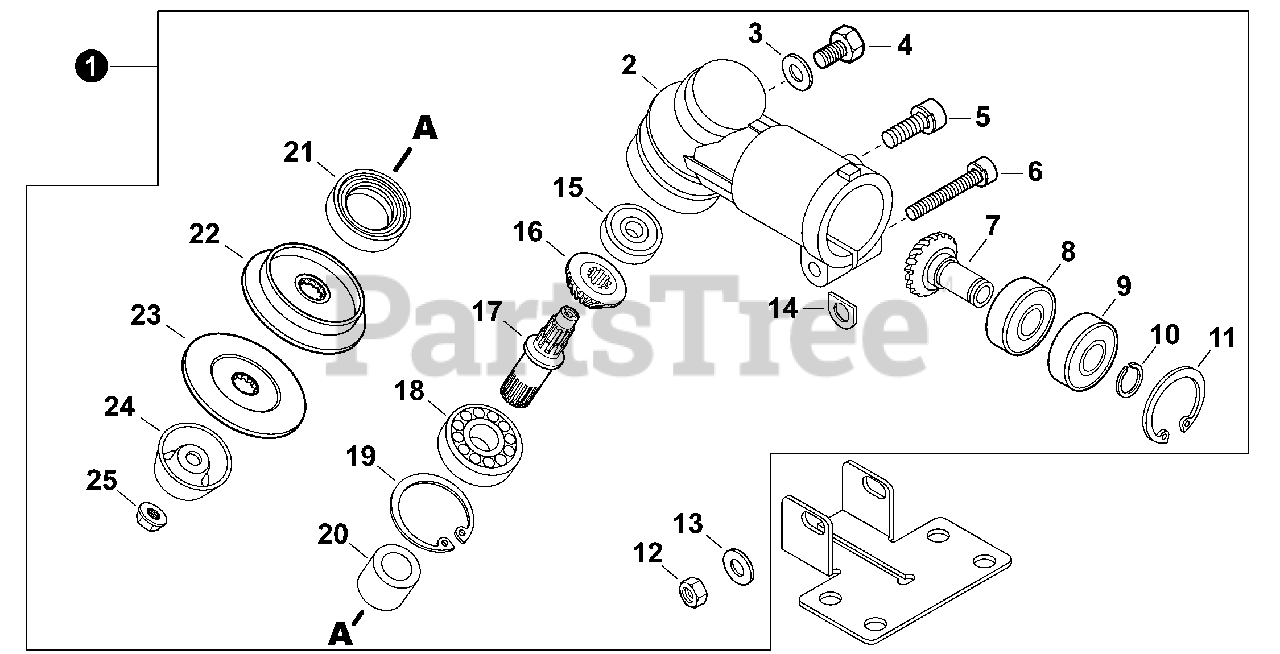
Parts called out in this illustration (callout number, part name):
1	GEAR CASE ASSY
2	HOUSING, GEAR CASE
4	BOLT M6×10
5	BOLT M5×16
6	BOLT M5×35
7	GEAR, PINION
8	BEARING, BALL 608
9	BEARING, BALL 608ZZ
10	E-RING 8
11	RING, SNAP Ø22
12	NUT M5
13	WASHER 5.5×12×0.8
14	D-WASHER
15	BEARING, BALL 626 DDU
16	GEAR, BEVEL
17	SHAFT, GEAR
18	BEARING, BALL 6001
19	RING, SNAP Ø28
20	COLLAR 10
21	SEAL, OIL
22	PLATE, ADAPTOR - UPPER
23	PLATE, ADAPTOR - LOWER
25	NUT, LOCK 10 - NYLON INSERT
